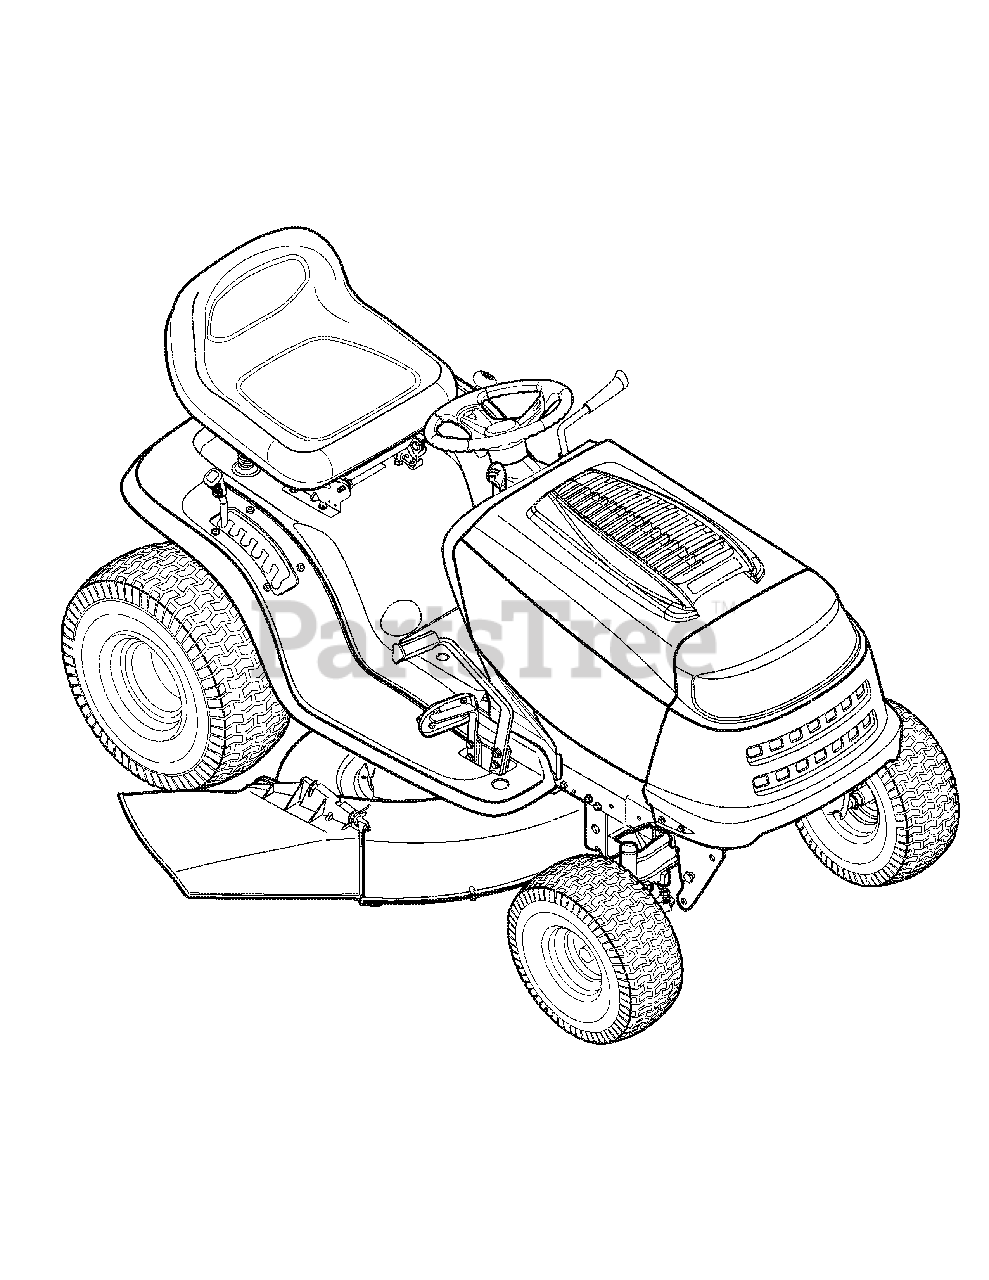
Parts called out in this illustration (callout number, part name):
NA	PRE-CLEANER ELEMENT
NA	ENGINE TO DECK BELT
NA	DECK WHEELS
NA	WATER NOZZLE ADAPTER
